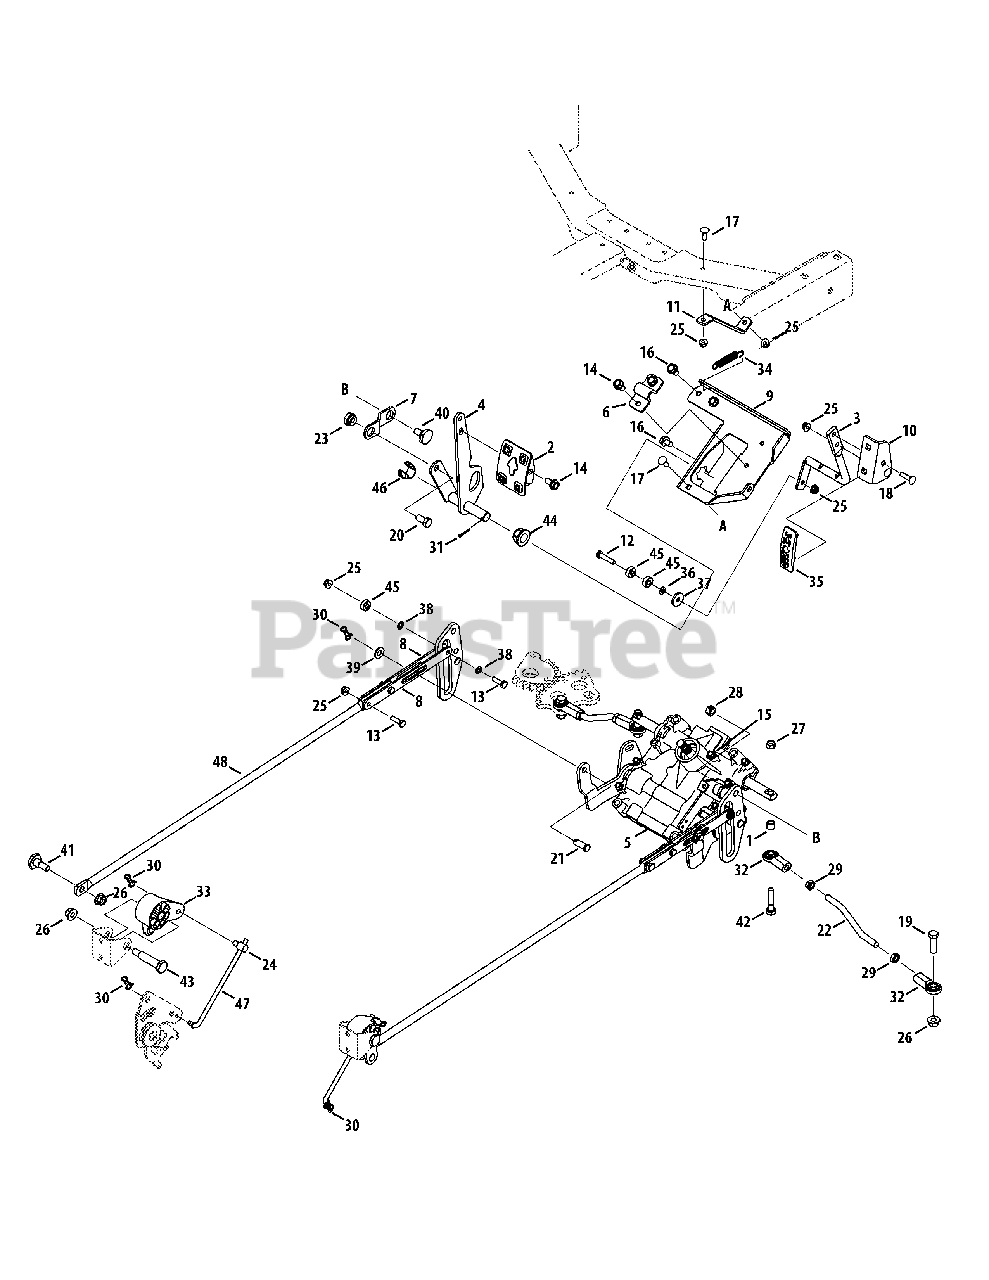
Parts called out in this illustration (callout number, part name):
1	Spacer, 344 x .500 x .375
2	Forward Pedal Assembly
3	Reverse Pedal Rod
4	Forward Bracket Assembly
5	Steering Assembly
6	Reverse Bearing Bracket
7	Control Bracket
8	Steering Link Plate
9	Pedal Mount Bracket
10	Reverse Pedal Bracket
11	Pedal Mount Plate Support Bracket
12	Hex Head Screw, 1/4-20 x 1.25
13	Hex Screw, 1/4-20 x .875
14	Hex Washer Screw, 5/16-18 x .750
15	Hex Washer Screw, 1/4-20 x .500
16	Hex Washer Screw, 5/16-18 x .625
17	Carriage Screw, 1/4-20 x .75
18	Carriage Screw, 1/4-20 x 1.00
19	Hex Screw, 3/8-16 x 1.25
20	Hex Screw, 3/8-16 x .750
21	Clevis Pin, .375 x .969
22	Rod, 3/8 x 5.0
23	Neutral Adjustment Hub
24	Adjustment Ferrule, 1/4-28 x 1.000
25	Flange Lock Nut, 1/4-20
26	Flange Lock Nut, 3/8-16
27	Hex Lock Nut, 5/16-24
28	Hex Lock Nut, 3/8-16
29	Jam Nut, 3/8-24
30	Bow-Tie Cotter Pin, 72
31	Cotter Pin, 3/32 x .750
32	Femaile Ball-Joint
33	Pivot Arm, LH
33	Pivot Arm, RH
34	Extension Spring, .429 x 2.515
35	Reverse Foot Pad
36	Flat Washer, .281 x .500 x .063
37	Flat Washer, .265 x .938 x .120
38	Flat Washer, .281 x .50 x .04
39	Thrust Washer, .375 x .812 x .060
40	Shoulder Screw, .625 x .217
41	Shoulder Screw, .500 x .434
42	Shoulder Screw, 375 x .48
43	Shoulder Screw, .500 x 1.825
44	Hex Flange Bearing
45	Ball Bearing, .25 x .6875 x .25
46	Hex Flange Bearing, .628
47	Hydro Control Rod
48	Hydro Link Rod
